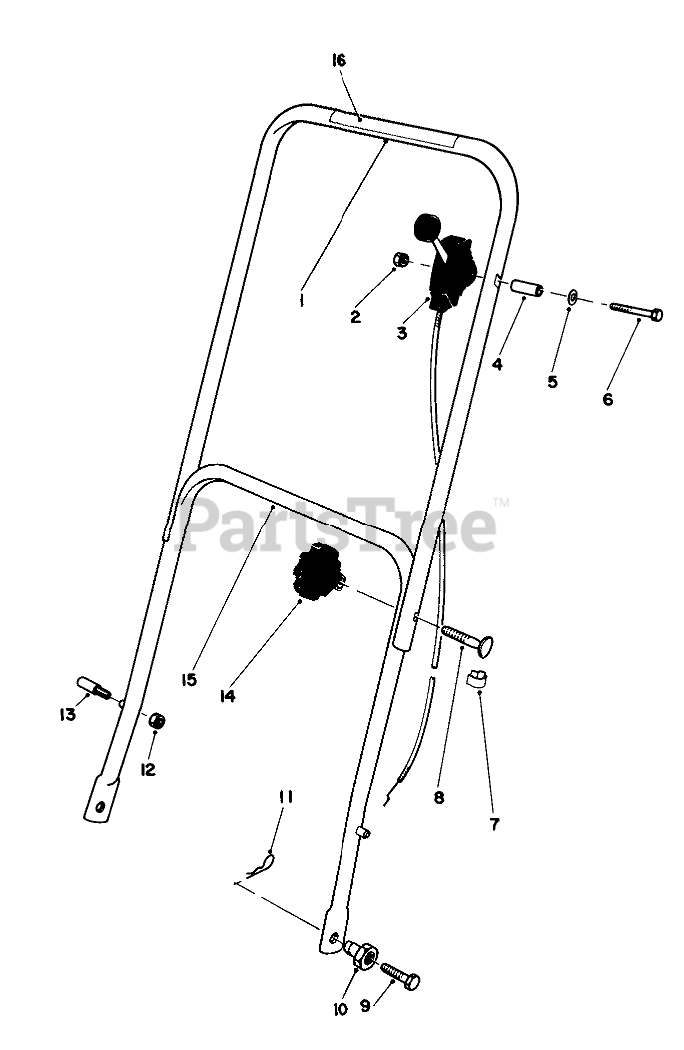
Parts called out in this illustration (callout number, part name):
1	Upper Handle (Incl. Ref. #16)
2	NUT-LOCK, NI
3	SERVICE THROTTLE CONTRO
4	Spacer
5	WASHER
6	SCREW-HH
8	5/16-18 X 2 HNDLE SCREW
9	SCREW-HH
10	HANDLE PIVOT NUT
11	PIN-COTTER, HAIR
12	NUT-LOCK, NI
13	HANDLE PIN
15	LOWER HANDLE ASM
16	Decal-Danger
